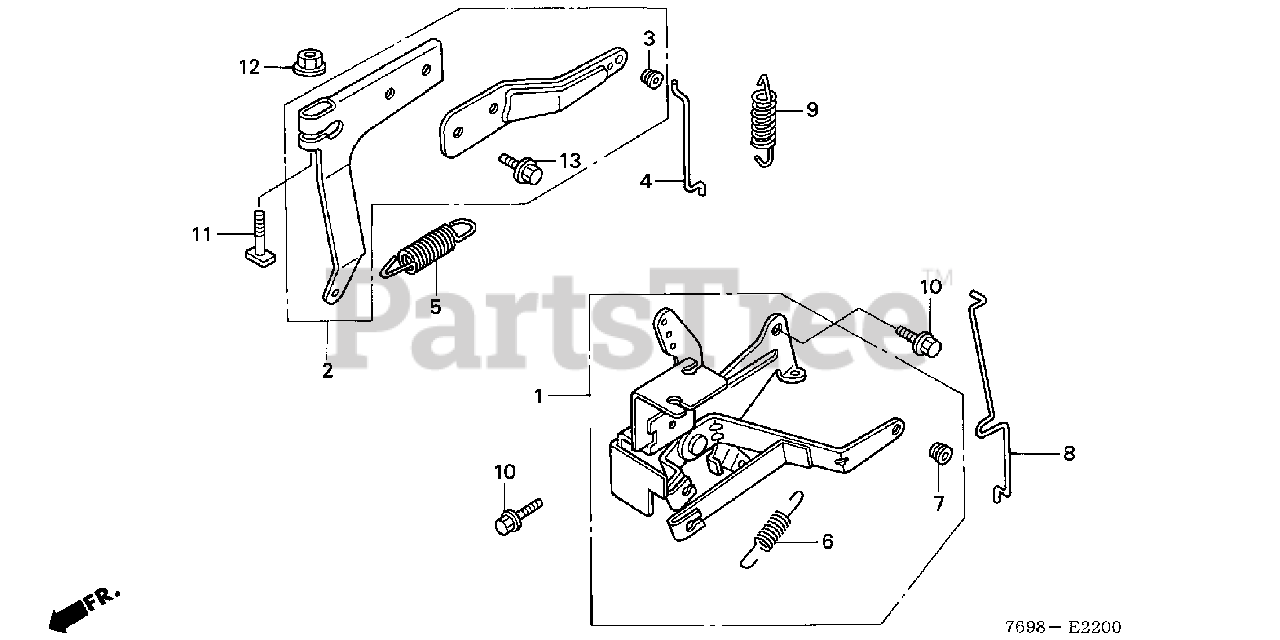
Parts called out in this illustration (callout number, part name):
2	ARM, GOVERNOR
3	COLLAR, LEVER
4	ROD, GOVERNOR
5	SPRING, GOVERNOR
6	SPRING, CONTROL LEVER RETURN
7	COLLAR, LEVER
8	ROD, CHOKE
9	SPRING, THROTTLE RETURN
10	BOLT, FLANGE (6X14)
11	BOLT, GOVERNOR ARM
12	NUT, FLANGE (6MM)
13	BOLT, FLANGE (6X8)
